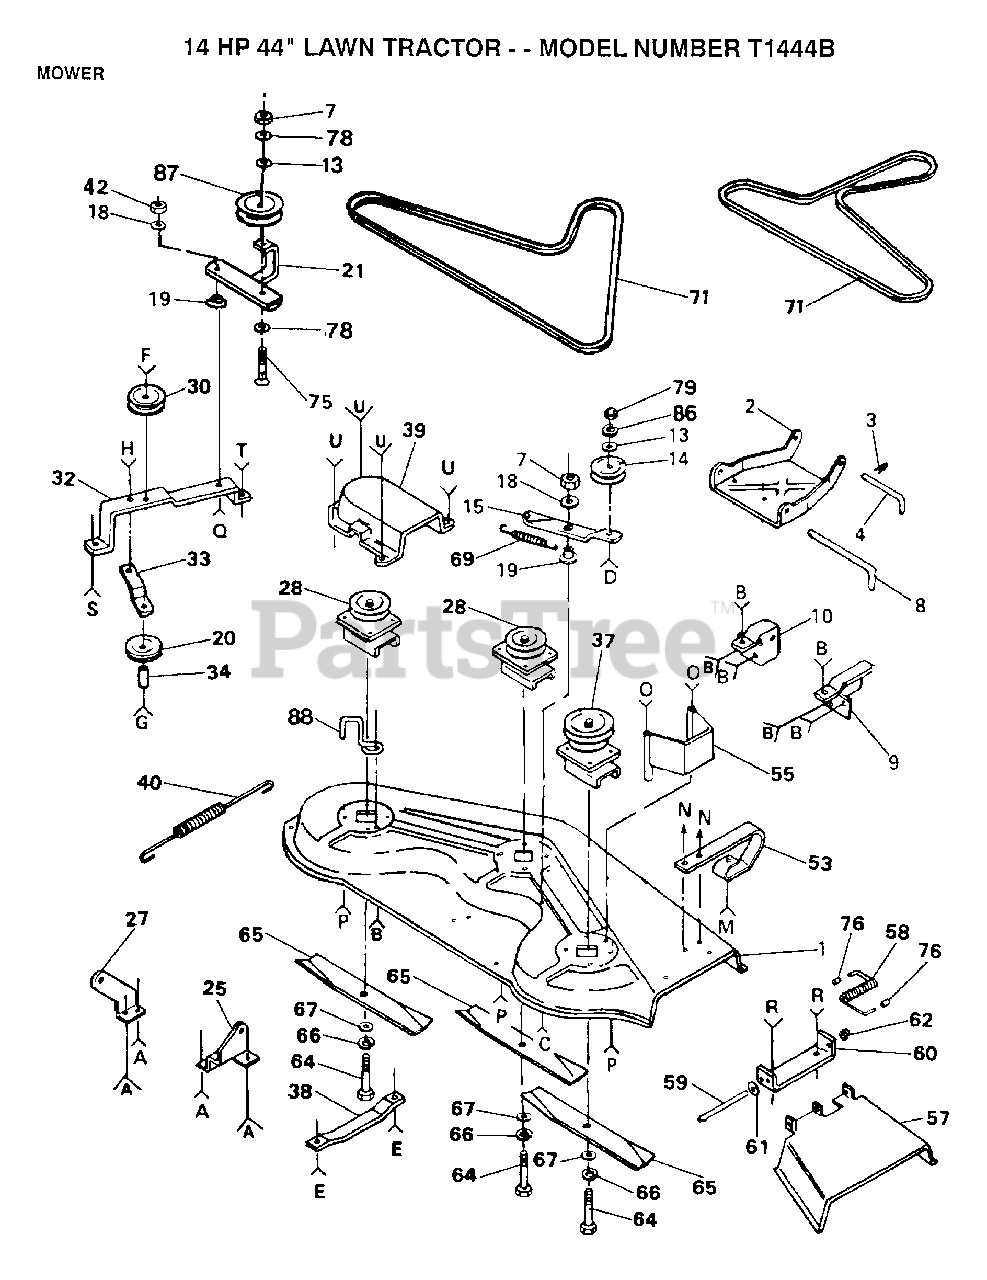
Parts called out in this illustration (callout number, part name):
2	"STOP, LINK PARAL"
3	SPRING.RETAINER
4	"ROD, FRT. PARAL T"
8	HINGE PIN T
9	BRACKET RH YT
13	WASHER
14	IDLER.FLAT.GTV
15	ARM-IDLER YT
18	"WASHER, WEAR LT"
19	SPACER RETAINER
20	IDLER-FLAT T
21	ARM IDLER
25	BRKT SUSP REAR RH
27	BRKT SUSP REAR LH
30	IDLER-INSIDE T
32	"SUPPORT YT, BAR"
33	BRACE-IDLER YT
34	SPACER
38	RUNNER-LH M
39	GUARD YT
40	"SPRING.EXT.8.5"""
42	LOCKNUT
55	GUARD BELT HYT
57	DEFLECTOR SHIELD
59	ROD-HINGE T
61	WASHER
62	NUT PUSH M
64	BOLT.3/8-24X1-1/2
67	WASHER
71	BELT-V.79.1.MWR
75	BOLT
76	CAP-SLEEVE LT
78	WASHER
79	NUT.HEX.3/8-16UNC
86	LOCKWASHER
87	PULLEY IDLER
88	BELT RETIANER
